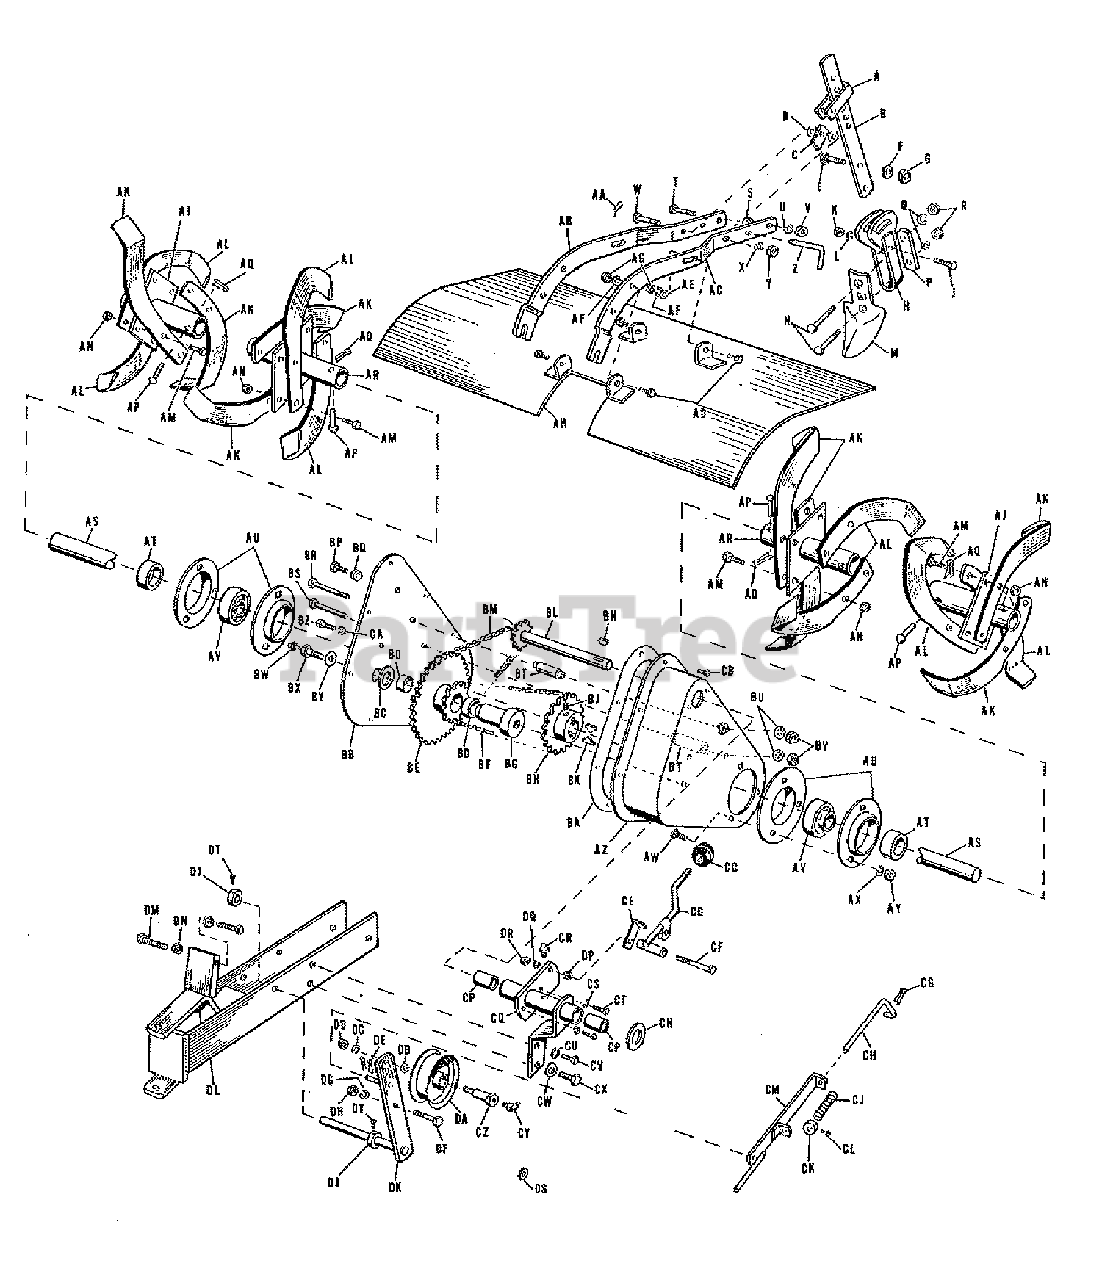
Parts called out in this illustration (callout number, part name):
B	BAR, Depth
C	LUG, Stop
E	BOLT, Carriage, 3/8-16 x 1-3/4 w/Short Square Neck
H	HOLDER ASSEMBLY, Tool
L	WASHER, Lock, 3/8" Regular
M	SHOE, Depth
P	STRAP, Shoe
Q	WASHER, Lock, 3/8" Regular
U	WASHER, Lock, 1/2" Regular
X	WASHER, Lock, 1/2" Regular
AA	CLIP, Spring
AB	BEAM, Depth Guage, R.H.
AC	BEAM, Depth Guage, L.H.
AF	WASHER, Lock, 3/8" Regular
AH	DEFLECTOR ASSEMBLY
AJ	PLATE ASSEMBLY, Tine, Outer
AK	BLADE, R.H. Tine
AL	BLADE, L.H. Tine
AN	NUT, Hex, Full Lock, 7/16-20 Gripco
AP	PIN, Tine Shaft
AR	PLATE ASSEMBLY, Tine Inner
AS	SHAFT, Tine
AT	COLLAR, Bearing, Fafnir #S-1102
AU	FLANGE, Bearing, Fafnir #62MS
AV	BEARING, Fafnir #RA102PPB
AX	WASHER, Lock, 3/8" Regular
AZ	GUARD ASSEMBLY, Chain
BB	PLATE ASSEMBLY, Side
BE	SPROCKET ASSEMBLY
BF	CHAIN, Rotor
BG	SPACER, Intermediate
BH	SPROCKET, Driven
BJ	SCREW, Hex Socket, Cup Point Set, 5/16-18 x 5/16"
BK	KEY, #HP-708 "HI-PRO"
BL	SHAFT ASSEMBLY, Drive
BM	CHAIN, Drive
BN	KEY, Woodruff #9, 3/16 x 3/4"
BP	SCREW, Square Head, Oval Point Set, 3/8-24 x 3/4"
BQ	NUT, Hex Jam, 3/8-24
BR	SCREW, Hex Head Cap, 7/16-14 x 4-1/2"
BS	SCREW, Hex Head Cap, 7/16-14 x 3-3/4"
BT	SPACER, Guard
BU	WASHER, Lock, 7/16" Internal Shakeproof
BW	FITTING, Grease, Alemite #1641
BY	WASHER, Plain, 7/16"
BZ	SCREW, Hex Head Cap, 3/8-16 x 3/4"
CA	WASHER, Lock, 3/8" Regular
CB	SCREW, 1/4-20 x 3/8" Hex Head Sems w/External Lockwasher
CC	BALL, Clutch Lever
CD	CLUTCH LEVER ASSEMBLY, R.H.
CE	STOP, Lever
CH	ROD, Idler Clutch
CK	COLLAR, Set
CM	GUIDE ASSEMBLY, Rod
CQ	SUPPORT ASSEMBLY, Housing
CS	WASHER, Lock, 5/16" Regular
CU	WASHER, Lock, 3/8" Internal Shakeproof
CY	FITTING, Grease, Alemite #1911-90 Degrees
CZ	PIN, Idler Pulley
DA	PULLEY ASSEMBLY, Idler
DC	WASHER, Lock, 1/2" Internal Shakeproof
DG	WASHER, Lock, 3/8" Regular
DJ	SET, Collar
DK	LEVER ASSEMBLY, Idler
DL	FRAME ASSEMBLY
DN	NUT, Hex, Full, 7/16-20 NF
DP	NUT, Hex, Jam, 5/16-18 NC
DQ	WASHER, Lock, 5/16" Regular
DS	WASHER, Plain,"
DT	SET SCREW, 5/16-18 x 3/8" Square Head Cup Point
